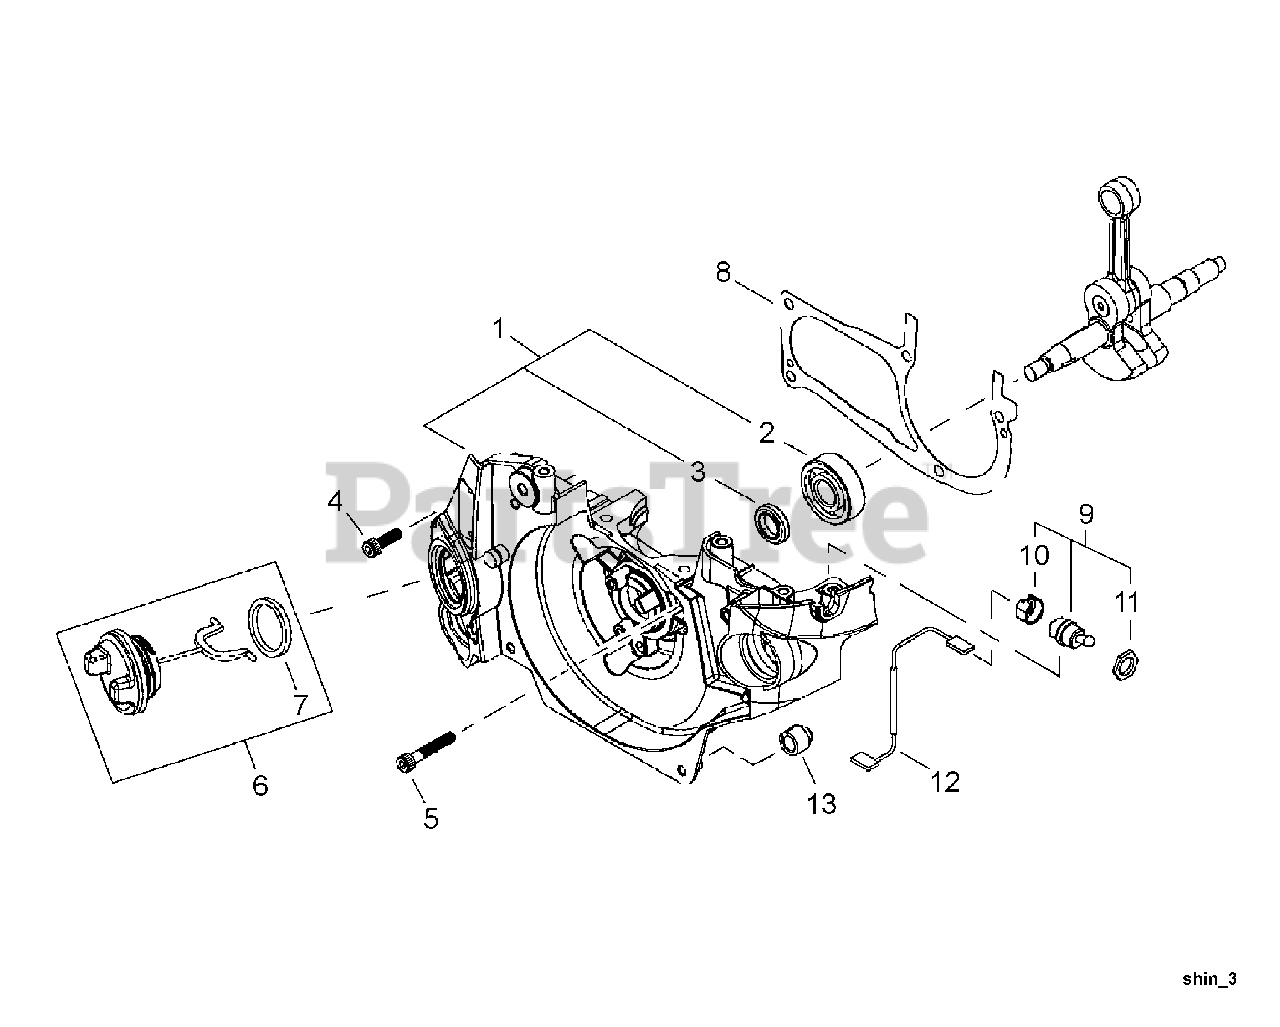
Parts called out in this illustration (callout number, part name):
1	CRANKCASE ASSY - FRONT
2	BEARING, BALL - 6201C3
3	SEAL, OIL - 12
4	SCREW - 5X18
5	BOLT - 5X35
6	CAP ASSY
7	GASKET, CAP
8	GASKET, CRANKCASE
9	IGNITION SWITCH ASSY
11	NUT
12	LEAD - IGNITION
13	SUPPORT
